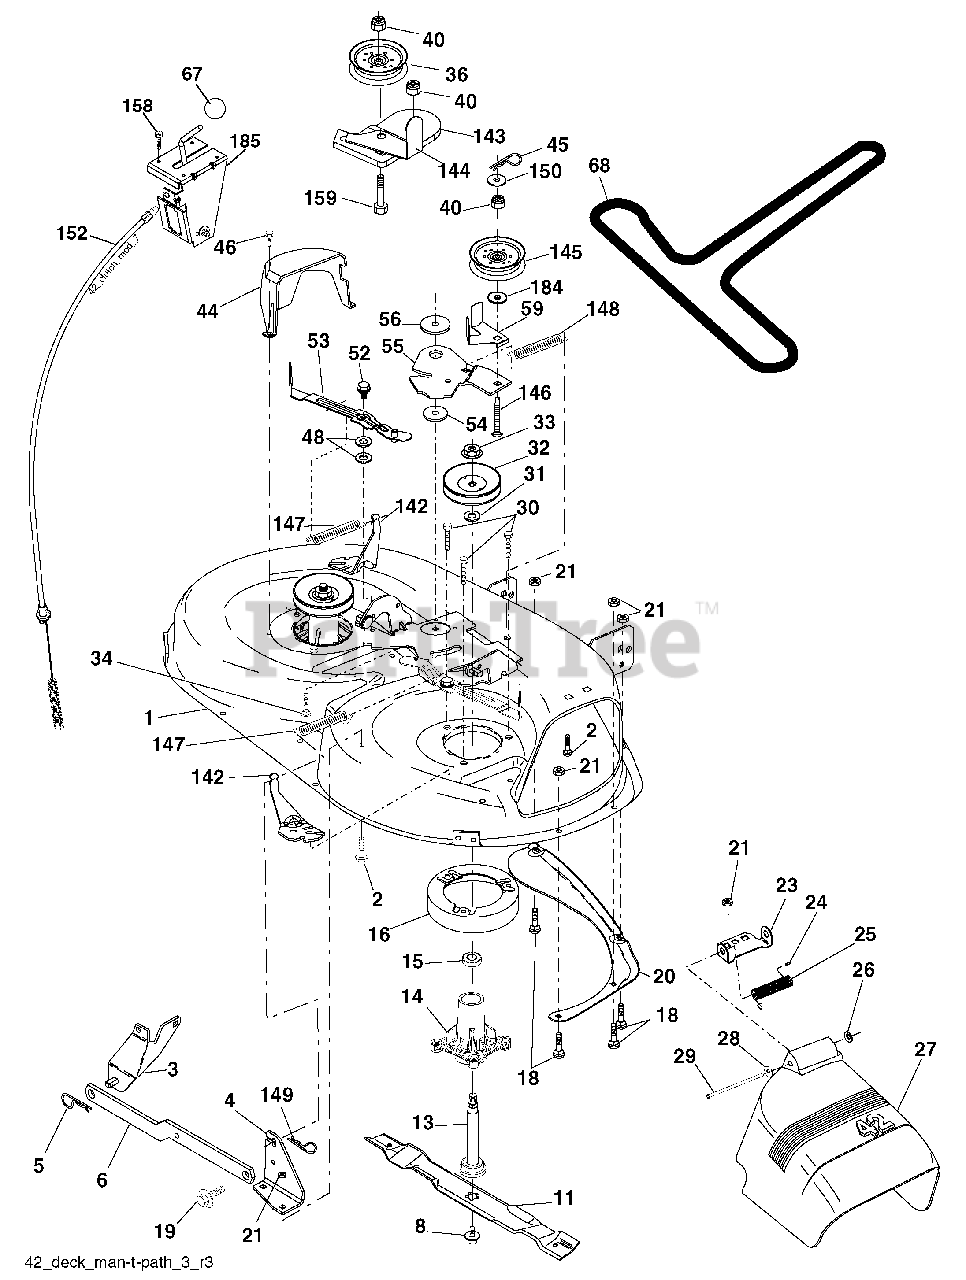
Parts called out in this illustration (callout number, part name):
1	Mower Deck Assembly, 42"
2	Bolt
3	Bracket Asm Fr. Sway Bar 3/42
4	Bracket Asm Deck 42" Sway Bar
5	Retainer Spring
6	Bar Sway Deck
8	Bolt 3/8-24 x 1.25 Gr. 8 Patched
9	Washer, Lock
10	Washer, Hardened (The following Blades are available)
11	Blade Mower 42” Hi-Lift (for bagging and discharging)
11	Blade, Mulching 42” Std (for mulching mowers only)
11	Blade Mulching 42” Premium (For better wear when mulching)
13	Shaft As sem bly, Mandrel, Vented
14	Housing, Mandrel, Vented
15	Bearing, Ball, Mandrel
16	Stripper, Mandrel Deck
18	Bolt, Carriage 5/16-18 x 5/8
19	Bolt, Shoulder
20	Baffle, Vortex
21	Nut
23	Bracket, Deflector Mower 42"
24	Cap, Sleeve 80 x 112 Blk Mower
25	Spring, Torsion, Deflector 2 52
26	Nut, Push Phos & Oil
27	Shield, Deflector 42" Blk
28	Washer 11/32 x 5/8 x 16 Ga.
29	Rod, Hinge 42" 6 75 W/G
30	Screw Thdrol
31	Washer, Spacer Mower Vented
32	Pulley, Mandrel
33	Nut, Toplock
36	Pulley, Idler, Flat
40	Nut Lock 3/8-16
44	Guard, Mandrel, LH
45	Retainer
46	Screw, Thdrol 1/4-20 x 5/8 T
48	Washer, Hardened
52	Bolt, Shoulder 5/16-18 unc
53	Arm Assembly, Pad, Brake
54	Washer, Hardened
55	Arm, Idler
56	Spacer, Retainer
59	Guard TUV Idler
67	Knob Round
68	V-Belt, 42" Mower
142	Arm Spring Brake Mower
143	Bracket Arm Idler 42"
144	Keeper Belt 42" Clutch Cable
145	Pulley Idler Flat
146	Bolt Carriage Idler
147	Spring Extension
148	Spring Return Idler
149	Retainer Spring Yellow
150	Washer 9/32 x 3/4 x 10 Ga.
152	Clutch Cable 42"
158	Screw Hex Thd Cut 1/4-20 x 1/2
159	Bolt Rdhd Sqn 3/8-16 unc x 1-3/4
184	Washer 13/32 x 7/8 x 10 Ga.
185	Head Asm Cable Clutch
211	Bolt Carr SH 3/8-16 x 1-1/2 Gr. 5
211	Mandrel Assembly
211	Replacement Mower, Complete
